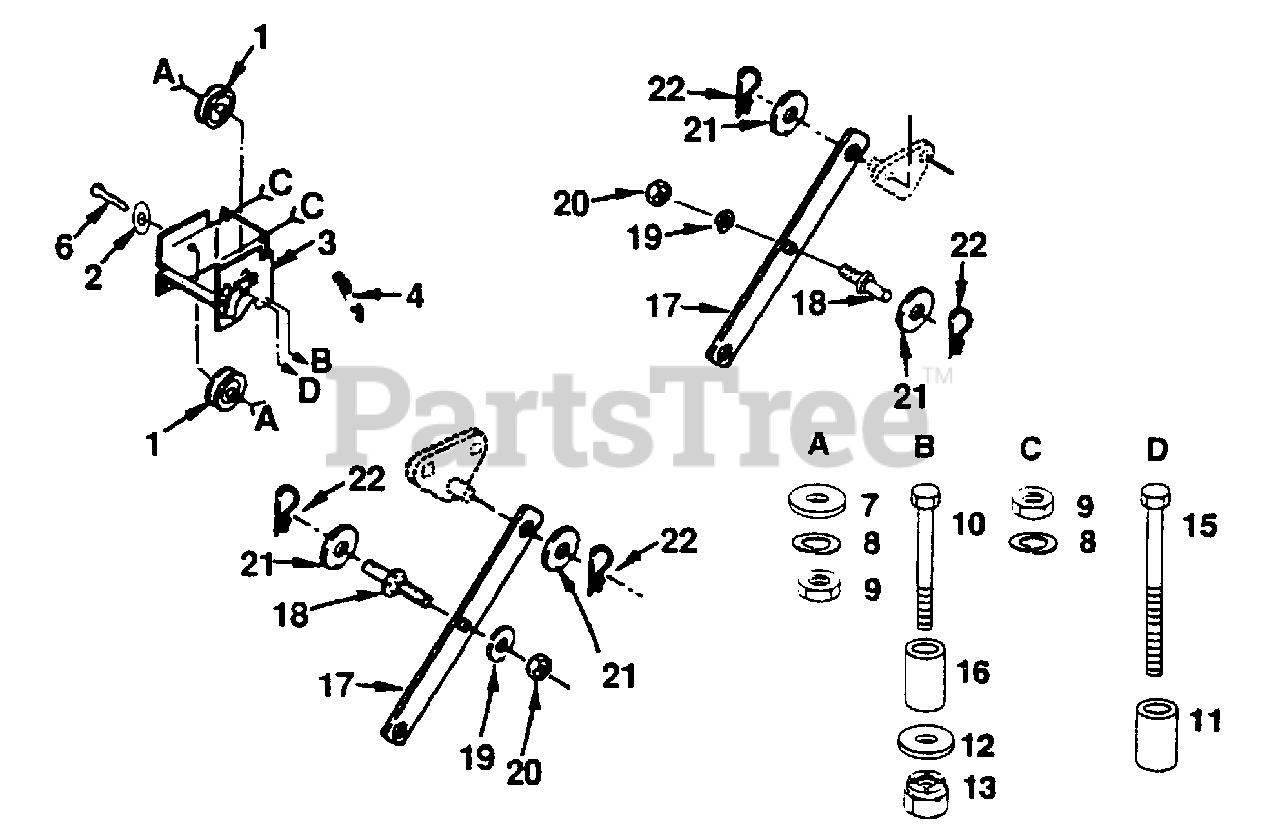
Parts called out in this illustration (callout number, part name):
1	Pulley, Idler
2	Washer 13/32 x 1-1/4 x 7 Gauge
3	Bracket, Idler
6	Bolt, Hex 3/8-16 x 2
7	Washer 13/32 x 7/8 x 13 Gauge
8	Washer, Lock 3/8
9	Nut, Hex 3/8-16
10	Bolt, Hex 5/16-18 x 1
11	Bushing, Handle, Clutch
12	Washer 11/32 x 7/8 x 16 Gauge
13	Nut, Crownlock 5/16-18
15	Bolt, Hex 3/8-16 x 2-1/4
17	Arm, Suspension
18	Stud, Pivot Center
19	Washer, Lock 1/2
20	Nut, Hex 1/2-13
21	Washer 17/32 x 1-1/6 x 13 Gauge
22	Retainer Spring
